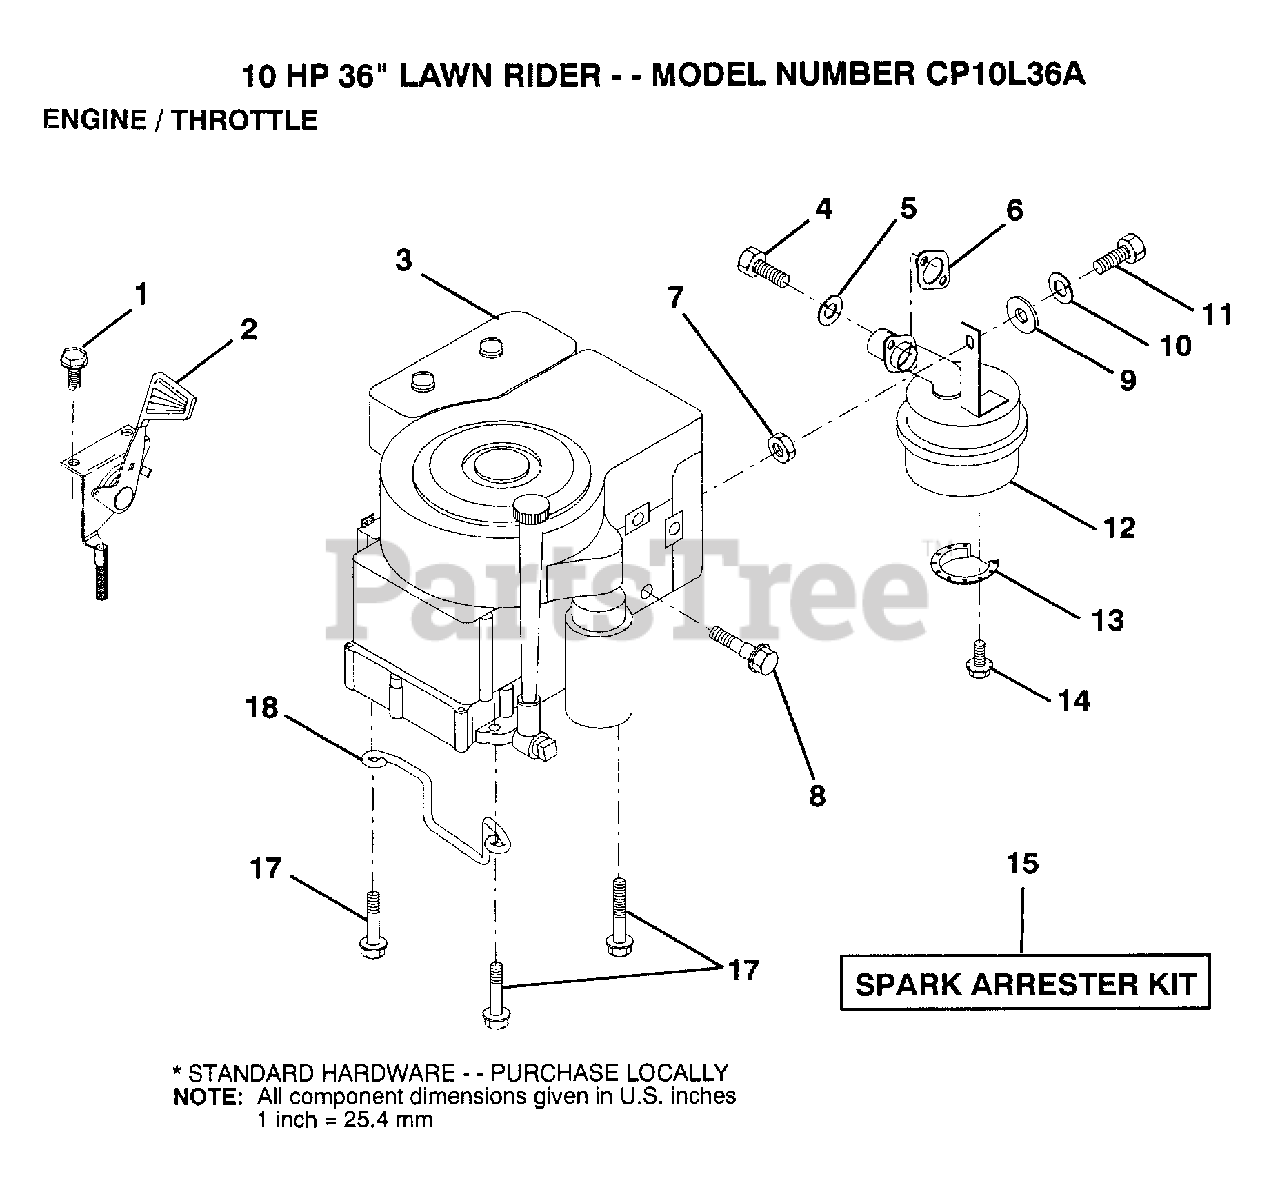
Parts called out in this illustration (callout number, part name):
1	SCREW
2	THROTTLE CONTROL
3	ENGINE BRIGGS AND STRATTON
4	SCREW
5	LOCKWASHER
7	NUT.HEX.5/16-18
8	BOLT T
10	LOCKWASHER
12	MUFFLER
13	DEFLECTOR.222573
17	SCREW LT
18	"KEEPER,DR BELT GR"
